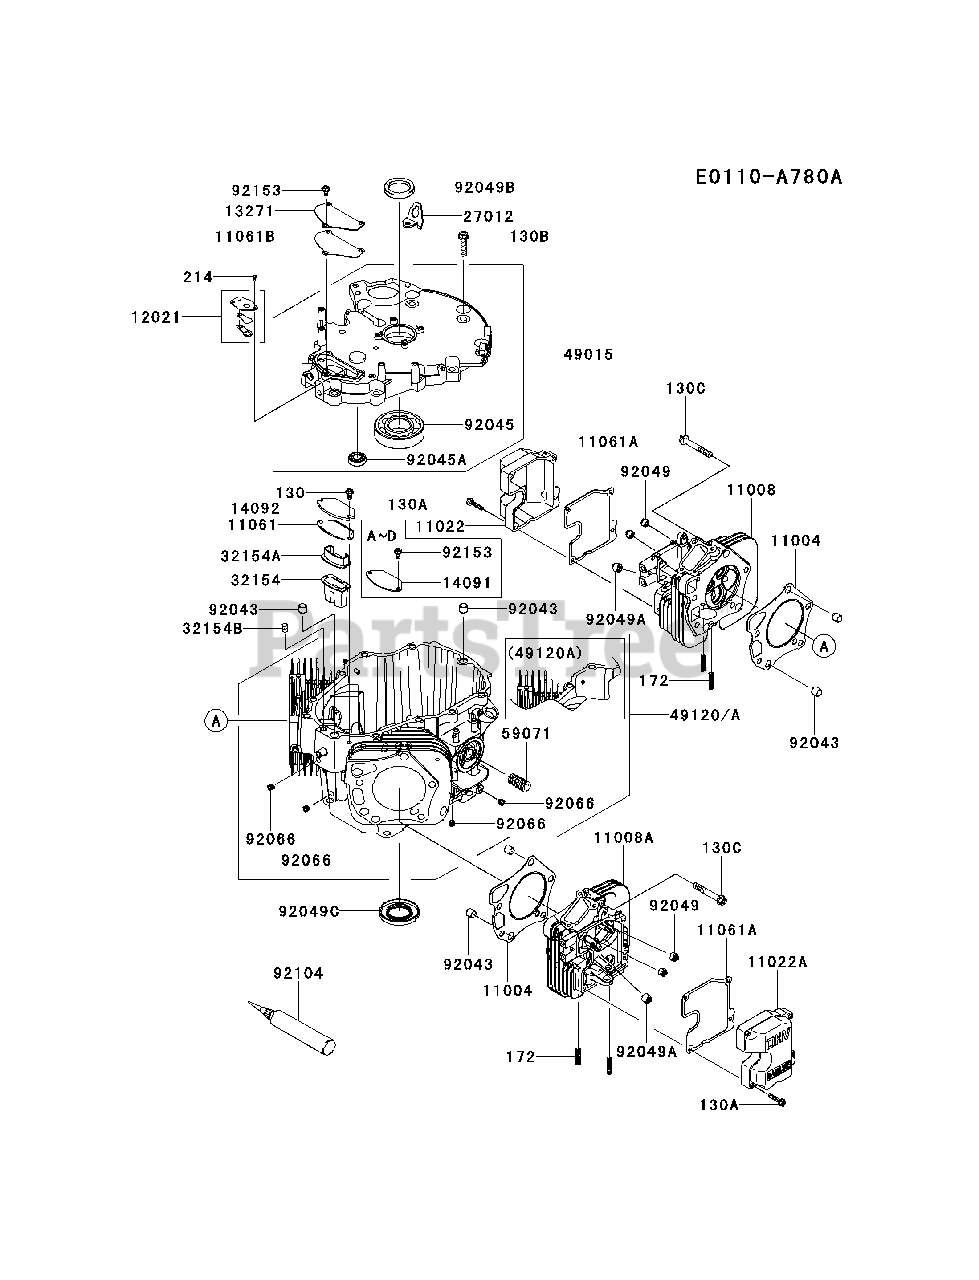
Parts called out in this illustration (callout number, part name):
130A	BOLT-FLANGED,6X30
130B	BOLT-FLANGED,10X40
130C	BOLT-FLANGED,10X65
172	BOLT-STUD,8X18
214	SCREW-PAN+-,4X8
